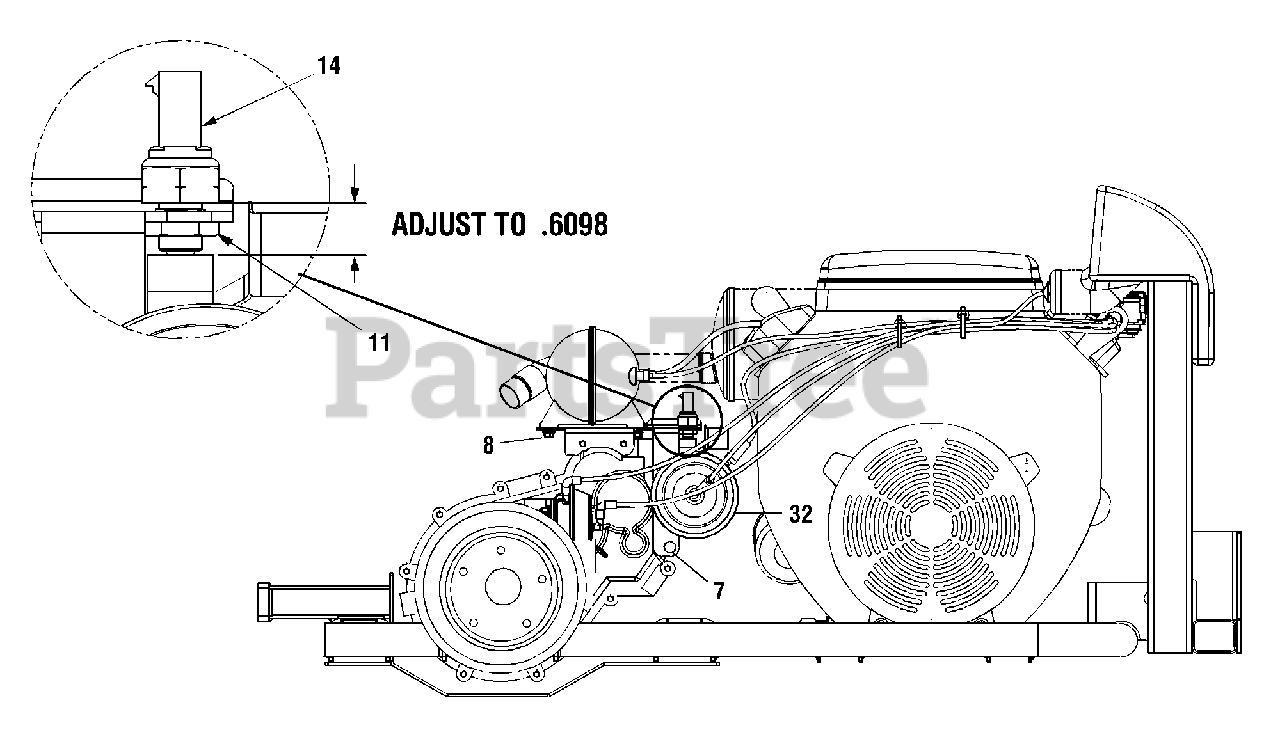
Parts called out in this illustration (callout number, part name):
7	Screw, 5/16-18
8	Screw, 1/4-14
11	Nut, Hex 9/16-18
14	Switch, Neutral
32	Actuator, Vacuum Shift
